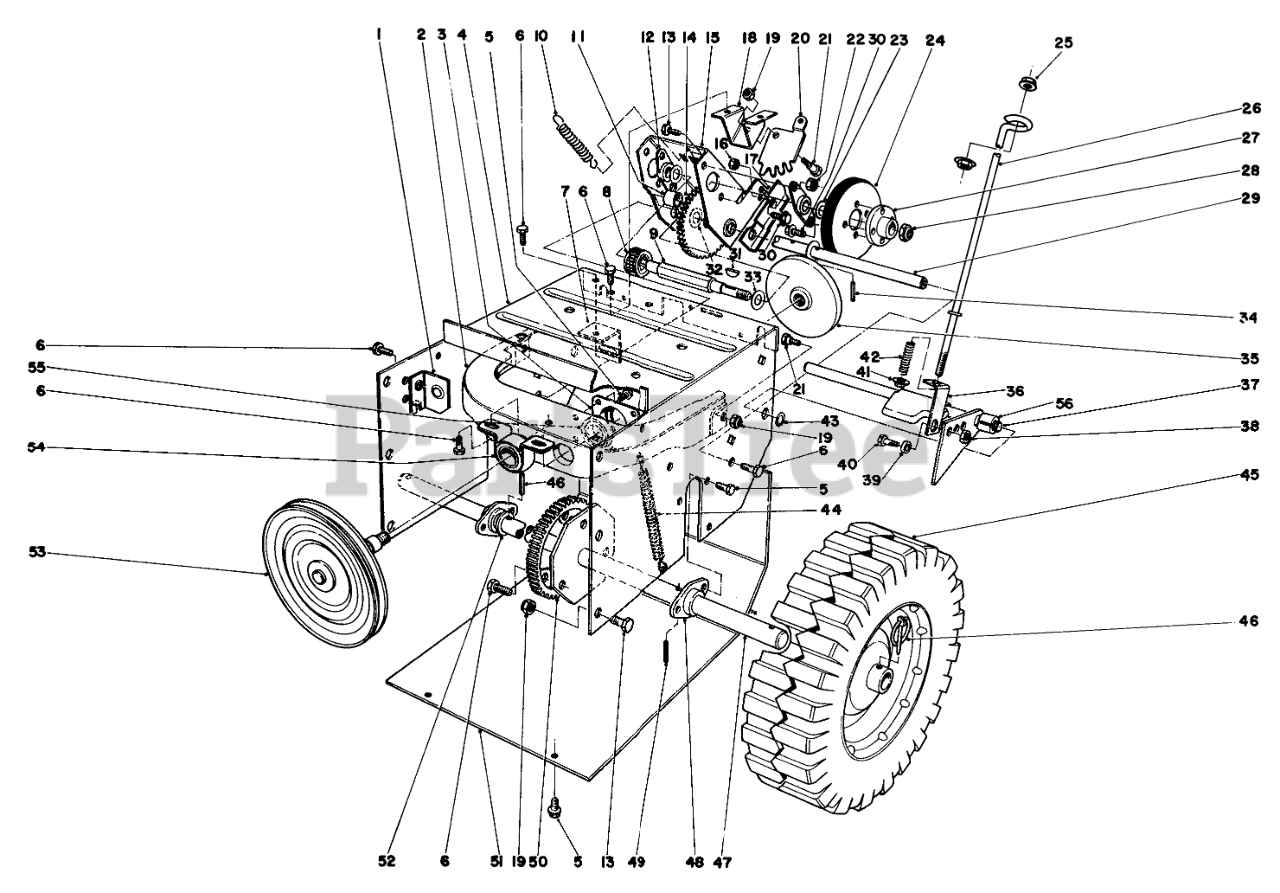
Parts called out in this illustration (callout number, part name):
1	AUGER CLUTCH MTG FRT
2	"OBS" FRICTION PLT FRAME
3	CUP-BEARING
4	Frame-Traction
5	SCREW
6	SCREW-HWHTF
7	BRACKET-MOUNT, REAR
8	PINION
9	SHAFT-WHEEL, FRICTION
10	SPRING-TRACTION
11	5/8ID X 1LG BUSHING
12	BEARING-WHEEL, FRICTION
13	SCREW-HH
14	Intermediate Gear (Incl. Ref. #11)
15	BRACKET-SLIDING
16	NUT-LOCK, NI
17	CAM-RECEIVER
18	MOUNT-LEVER
19	NUT-LOCK, NI
20	GEAR-QUADRANT
21	BOLT-SHOULDER
22	NUT-LOCK, CONE
23	WASHER-THRUST
24	WHEEL-FRICTION
25	NUT-HF
26	ROD-TRACTION, LOWER
27	HUB-WHEEL, FRICTION
28	NUT-LOCK, NI
29	SHAFT-PIVOT
30	Screw
31	KEY-WOODRUFF
32	WASHER-SPECIAL
33	WASHER-FLAT
34	PIN-SPRING
35	PLATE-FRICTION
36	BRACKET-TRACTION
37	TRACTION ENGAGE WA
38	NUT-LOCK, CONE
39	Spacer-Traction Bracket
40	SCREW-HH
41	NUT-LOCK, HHF
42	SPRING
43	RING-RETAINING
44	SPRING-PLATE, FRICTION
45	Wheel
46	PIN-LYNCH
47	AXLE SHAFT WA
48	BEARING-AXLE
49	PIN-SPRING
50	GEAR-AXLE
51	Bottom Cover
52	WASHER-THRUST
53	Pulley & Shaft
54	BUSHING ASM
55	BEARING-BALL
56	SPACER
